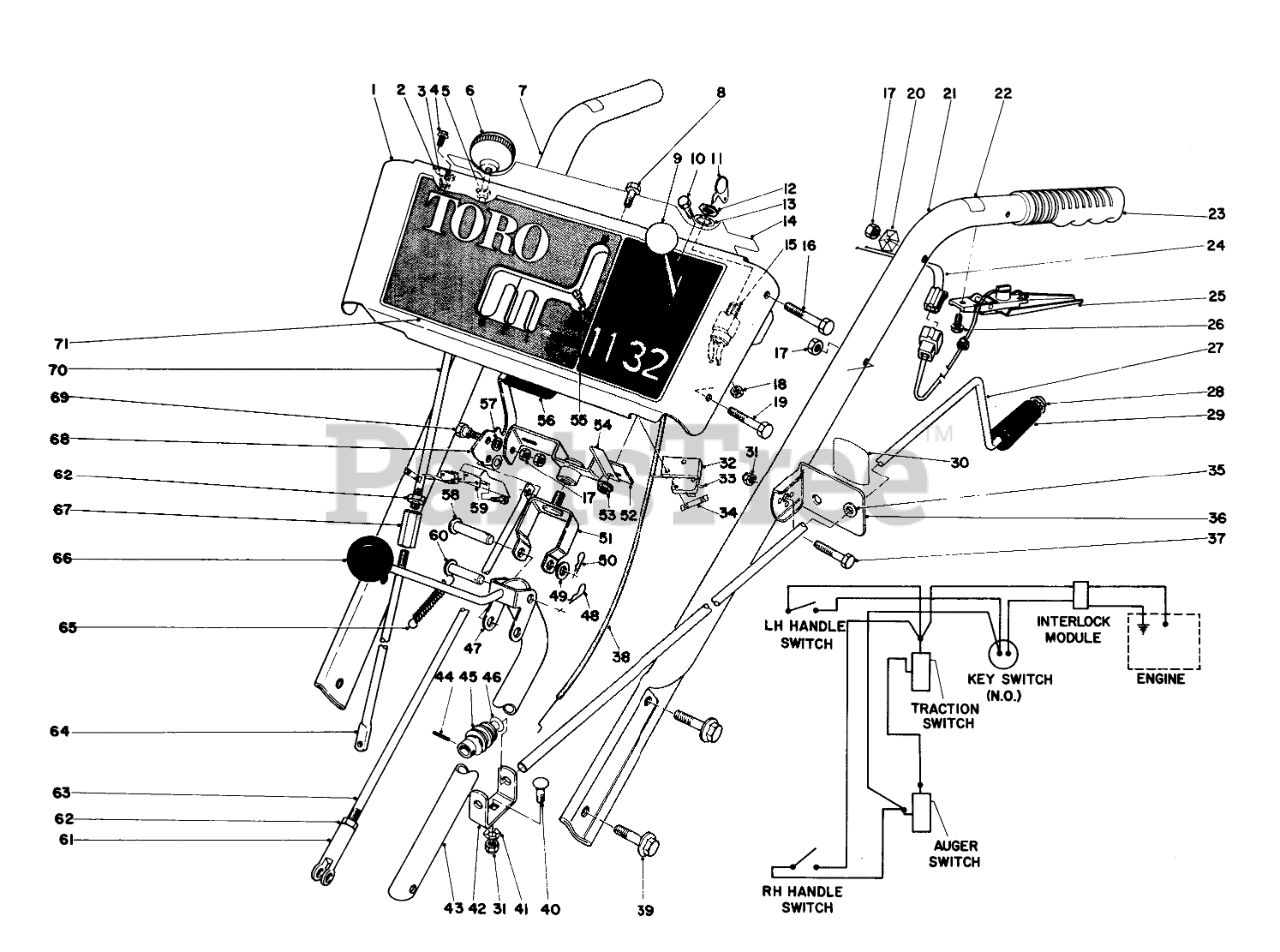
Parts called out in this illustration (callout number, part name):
1	Escutcheon Plate (Incl. Ref. #14 & 71)(Model 38090)
2	CLAMP-NYLON
3	NUT-KEPS
5	NYLINER #6LI-FF TYPE 7
6	KNOB-LEVER
7	Handle Right
8	SCREW-HH
9	CONTROL KNOB
10	HEX HEAD SEMS 10-24X1/2
11	Key
12	NUT-HH
13	WASHER-TOOTH, INTERNAL
14	BACK ESCUTCH DECAL
15	Key Switch
16	SCREW-HH
17	NUT-LOCK, CONE
18	Nut
19	SCREW-HH
20	Washer
21	HANDLE LEFT
22	INTERLOCK DECAL
23	Grip Handle
24	WIRE HARNESS INTERLOC
25	INTERLOCK HDLE SWITCH
26	SCREW
27	Chute Control Rod
28	RETAINER-PUSH ON
29	GRIP-CONTROL, CHUTE
30	CHUTE DECAL
31	NUT-LOCK, NI
32	SWITCH MTG PAD
33	SWITCH-MICRO
34	NUT-SPEED
35	Bushing
36	Bracket-Chute Control Mtg. (Incl. Ref. #30 & 35)
37	SCREW-HH
38	Throttle Contrl
39	SCREW-HHF
40	BOLT-CARR
41	WASHER-LOCK
42	WORM BRACKET
43	Rod Traction Shift
44	PIN-SPRING
45	GEAR-WORM, CHUTE
46	WASHER-SPRING
47	SHIFT ROD WA
48	PIN-COTTER
49	WASHER-FLAT
50	PIN-HAIR
51	PIVOT BRKT WA
52	SWIVEL BLOCK WA
53	NUT-LOCK, HHF
54	Retainer Wire
55	SCREW-SPH
56	AUGER CLUTCH HND GRIP
57	WASHER-PLAIN
58	PIN-CLEVIS
59	SWITCH BRKT
60	PIN-CLEVIS
61	Clevis
62	NUT-HJ
63	DRAG LINK
64	LOWER WHL CLUTCH ROD
65	CONT ROD SPRING 0
67	WHL ROD COUPLING
68	Auger Clutch Handle
69	SCREW-SHOULDER
70	UP WHEEL CLUTCH ROD
71	ESCUTCHEON DECAL
